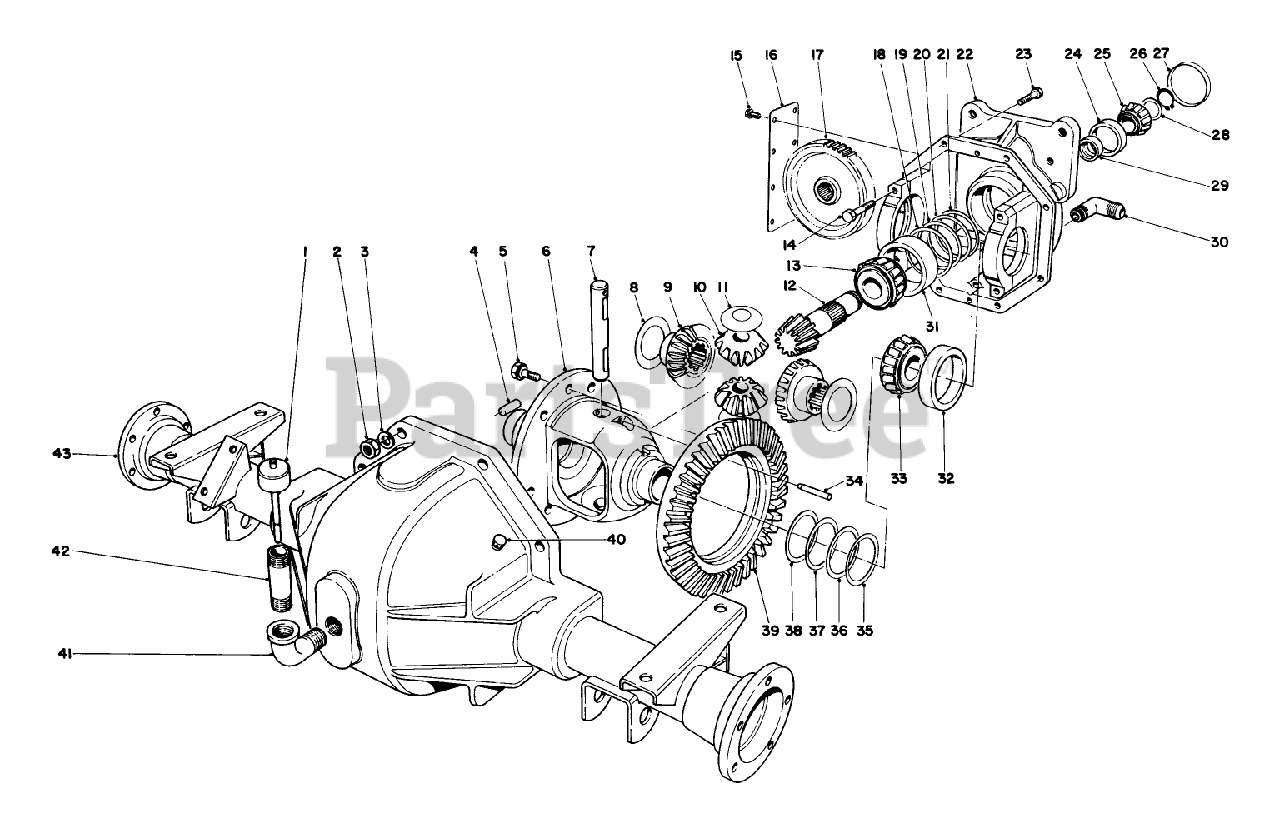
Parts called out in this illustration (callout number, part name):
1	DIPSTICK
2	NUT-HEX
3	WASHER-LOCK
4	PIN-DOWEL
5	SCREW-GEAR, DRIVE
6	CASE-DIFFERENTIAL
7	SHAFT-MATE, PINION
8	WASHER-THRUST
9	GEAR-DIFFERENTIAL
10	PINION-DIFFERENTIAL
11	WASHER-THRUST, PINION
13	BEARING-ROLLER, CONE TAPER
14	SCREW-HH
15	SCREW
16	COVER-GEAR
17	Gear-Spur
18	SHIM-PINION (.003)
19	SHIM-PINION (.005)
20	SHIM-PINION (.010)
21	SHIM-PINION (.030)
22	Upper Housing Assembly (Incl. Ref. #14)
23	SCREW-HH
24	BEARING-CUP
25	CONE-BEARING
26	RING-SNAP
27	PLUG-CUP
28	SHIM-BEARING, FRONT
29	SPACER-BEARING
30	90 DEG FITTING
31	BEARING-TAPER, CUP
32	CUP-BEARING, ROLLER
33	BEARING-ROLLER, CONE
34	PIN-ROLL
35	SHIM-BEARING, DIFFERENTIAL (.003)
36	SHIM-BEARING, DIFFERENTIAL (.005)
37	SHIM-BEARING, DIFFERENTIAL (.010)
38	SHIM-BEARING, DIFFERENTIAL (.030)
39	Ring Gear
40	VENT TUBE ASM
41	FITTING-ELBOW-90
42	PIPE NIPPLE
43	HSG TUBE & PAD LWR B
